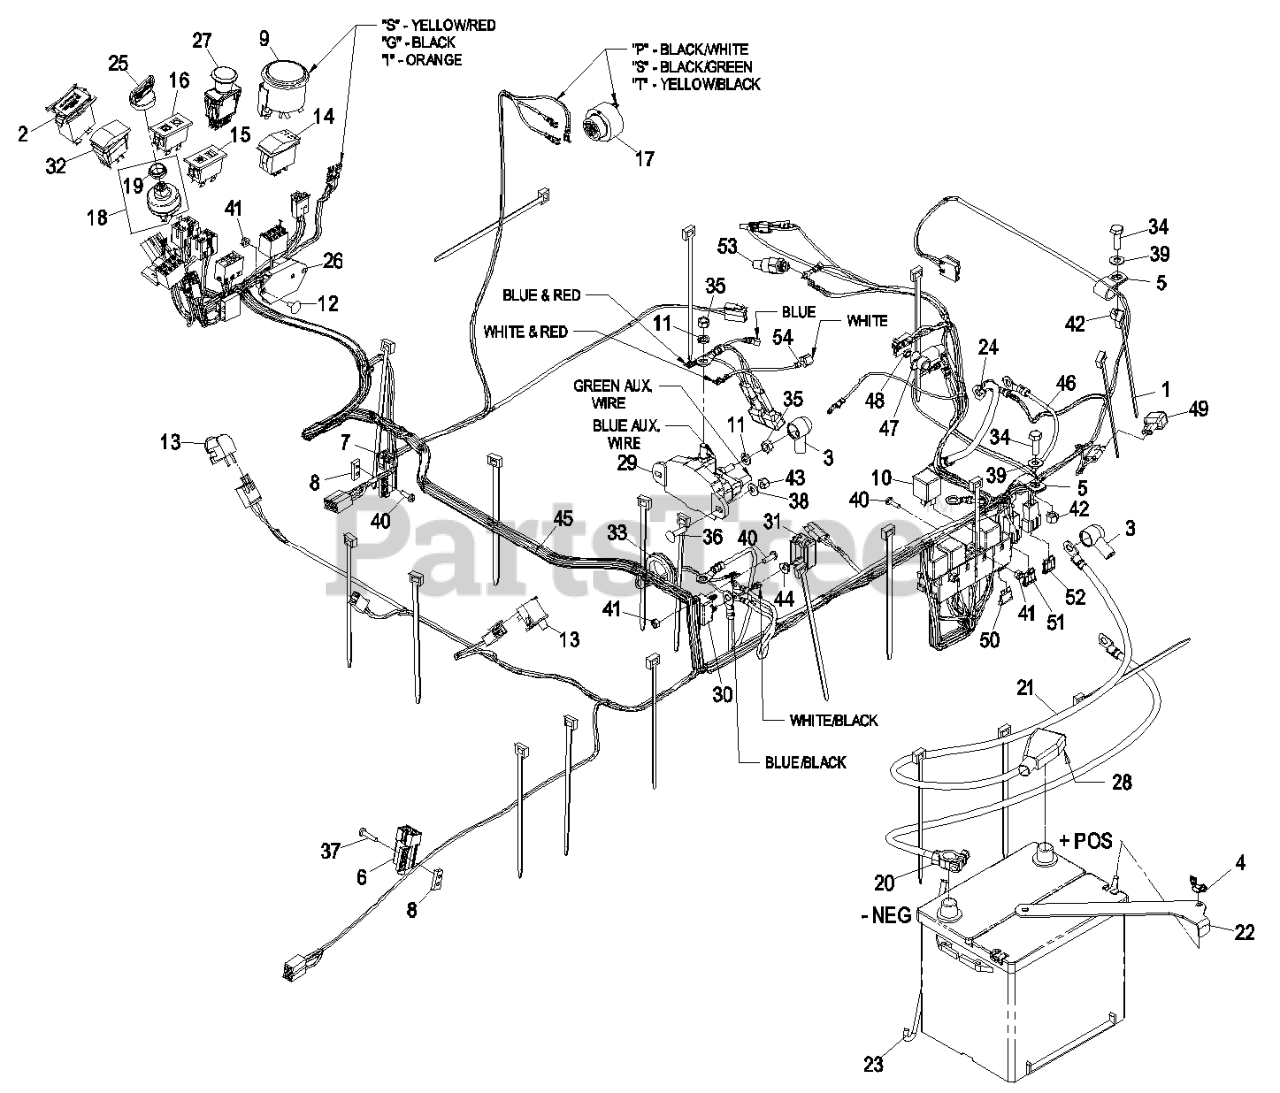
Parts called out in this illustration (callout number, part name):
1	TIE-PLASTIC
2	METER-HOUR
3	INSULATOR-SOLENOID
4	WINGNUT
5	CLIP-LOOM
6	SWITCH-BRAKE
8	PLATE-TAPPED
9	GAUGE-TEMPERATURE
11	WASHER-LOCK
12	BOLT-CARR
13	SWITCH-BAIL
14	SWITCH,ROCKER (ON)-NONE-(
15	LAMP-WARNING
16	LAMP-WARNING
17	ALARM-TONE, DUAL
18	ASM,SWITCH W/NUT
19	NUT-SWITCH, IGNITION
20	CABLE-BATTERY NEGATIVE
21	ASM,POSITIVE BATTERY CABL
22	STRAP, BATTERY
23	BOLT-HOLDDOWN
24	CABLE-ENGINE NEGATIVE
25	KEY-IGNITION
26	MODULE-DELAY, SEAT
27	SWITCH-PTO
28	INSULATOR-TERMINAL, BATTE
29	CONTACTOR, REVERSING POLA
30	CIRCUIT BREAKER,40A
31	COVER,CIRCUIT BREAKER
32	SWITCH-ROCKER
33	GROMMET-RUBBER
34	SCREW-HH
35	NUT-HEX
36	SCREW-CARR
37	SCREW-PPH
38	WASHER-FLAT
39	WASHER-PLAIN
40	SCREW-PPH
41	NUT-LOCK, NI
42	NUT-LOCK, NI
43	NUT-LOCK, NI
44	NUT-KEPS
45	HARNESS,WIRING FMZ KD902
46	HARNESS,AUX HYDRAULICS
47	CAP-INSULATOR, RED
48	NUT-HEX
50	FUSE-BLADE, 15 AMP
51	FUSE-BLADE TYPE, 20 AMP
52	FUSE-40 AMP
53	SENDER,TEMPERATURE
